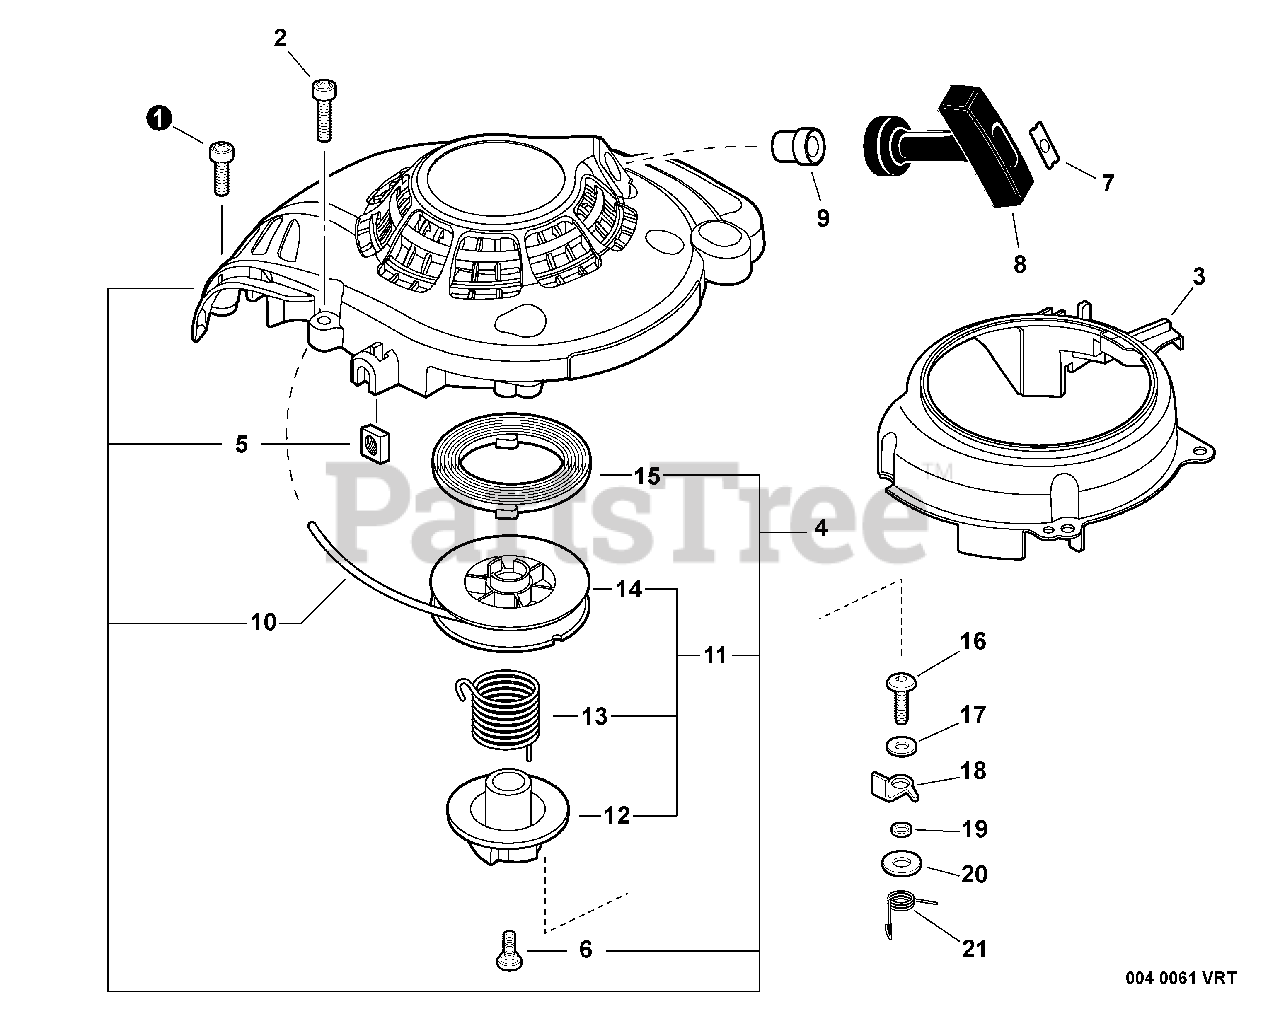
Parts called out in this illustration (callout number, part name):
1	SCREW - 4X12
2	SCREW - 4X16
3	COVER, FAN
4	STARTER ASSY - RED
5	NUT - 5 -- SQUARE
6	SCREW
7	RETAINER, ROPE
8	GRIP, STARTER
9	GUIDE, ROPE
10	ROPE, STARTER
11	ROPE REEL KIT
12	CATCHER, PAWL
13	SPRING, DAMPER
14	REEL, ROPE
15	SPRING, REWIND
16	SCREW - 5X14
17	WASHER - 5
18	PAWL, STARTER
21	SPRING, RETURN
